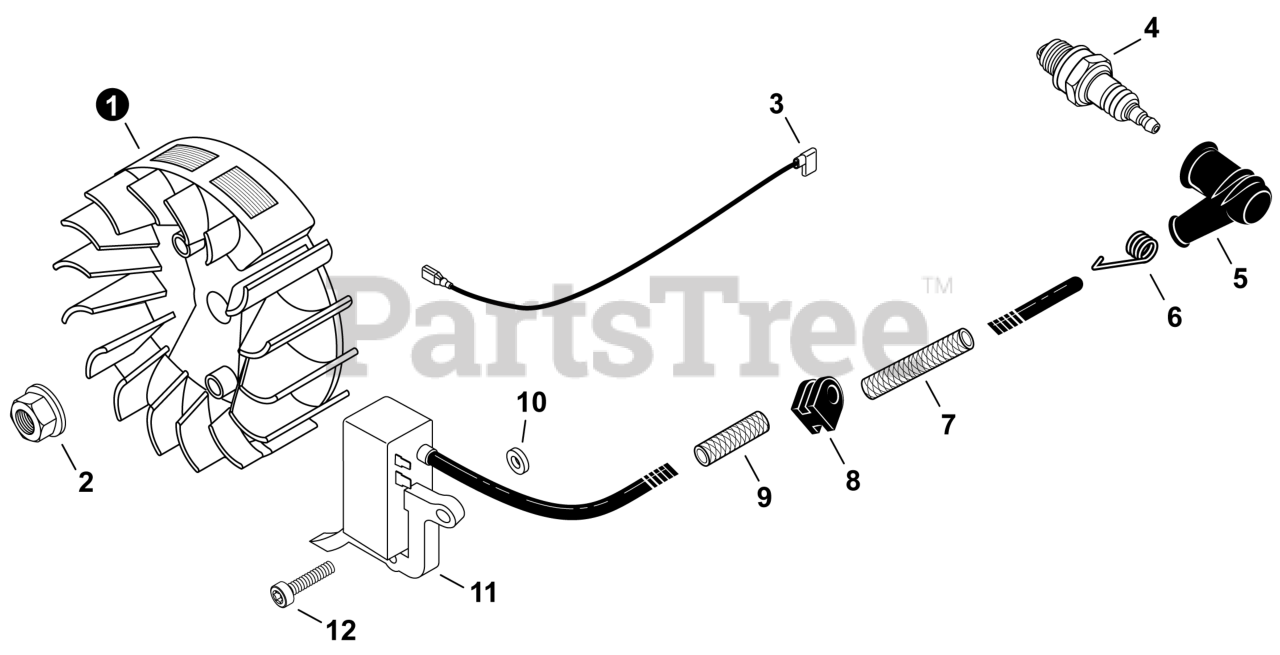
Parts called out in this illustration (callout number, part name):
1	FLYWHEEL
2	NUT, FLANGE M8
3	LEAD - IGNITION
4	SPARK PLUG - BPMR8Y
5	CAP, SPARK PLUG
6	TERMINAL, SPARK PLUG
7	TUBE, INSULATOR 7x8.6x40
9	TUBE, INSULATOR 7x8.6x30
10	WASHER 5.2x12x3
11	COIL, IGNITION
12	BOLT, TORX 5x20
